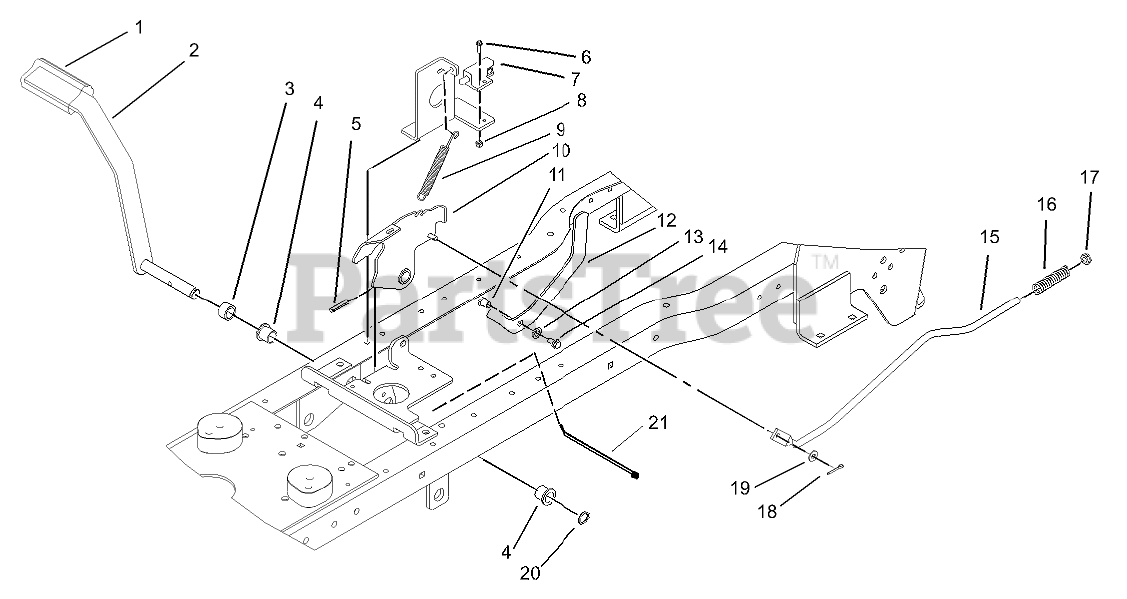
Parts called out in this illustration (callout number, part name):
1	PAD-PEDAL
2	BRAKE PEDAL ASM
3	SPACER-BRAKE
4	BUSHING-FLANGE
5	PIN-SPRING
6	SCREW-SHH
7	SWITCH-POLE, SINGLE
8	NUT-LOCK
9	SPRING-EXTENSION
10	Brake ASM
11	POST-MOUNTING, LINKAGE
12	LEVER, BRAKE-PARKING
13	SPACER-BRAKE, PARKING
14	SCREW-HHF
15	ROD-BRAKE
16	SPRING-COMPRESSION
17	NUT-HEX
18	PIN-COTTER
19	WASHER-FLAT
20	RING-RETAINING
21	TIE-CABLE
